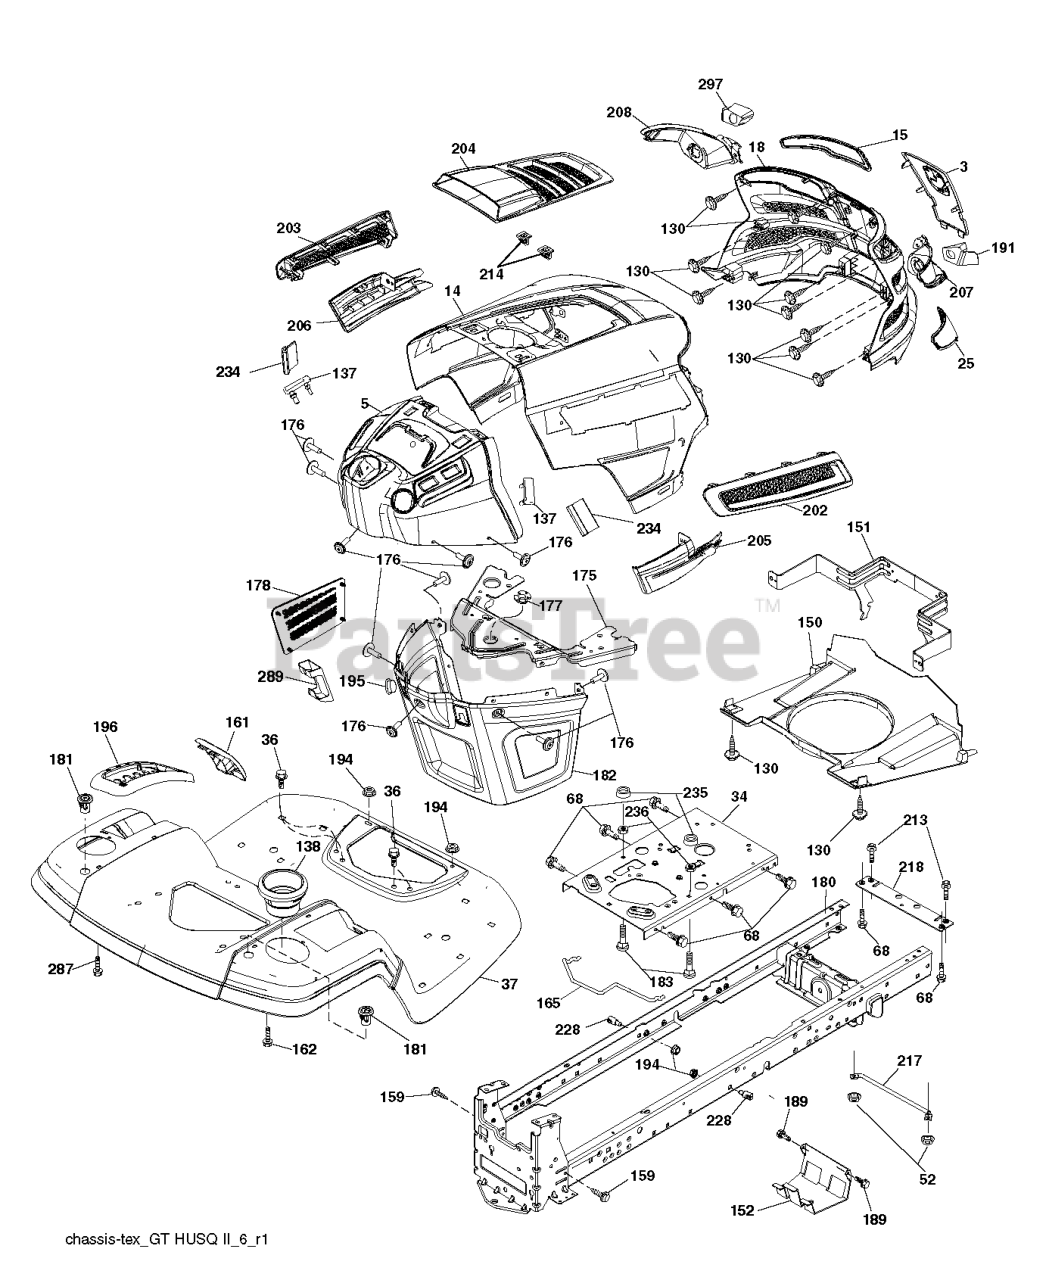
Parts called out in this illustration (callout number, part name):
3	APPLIQUE.SUBASM.GT.HUSQ.II
5	RP.DASH.UPP.GT2.SM.MC.CHOKE
14	HOOD.ASM.HUSQVARNA.GT.TEX.ORAN
15	LENS.HEADLIGHT.LH.GTII.2011
18	GRILLE.SUBASM.GT.HUSQ.II
25	LENS.HEADLIGHT.RH.GTII.2011
34	PLATE.ENGINE.WELDED.CHASSIS
36	SCREW 5/16"
37	FENDER.TLT.FS.W/CPH/FW/RSF.668
52	LOCKNUT
68	Screw 5/16-18 x 1/2 Hex, Self Tapping 5/16-18 x 1/2
130	SCREW.#10 X 0.750.BOS
137	BUMPER DASH
138	HOLDER.CUP.LT.GREY
150	AIR.DUCT.GTV2(2.54"RING HEIGHT
151	BRACKET.PIVOT.HOOD.GT.HUSQ.II
152	SHIELD.BROWNING.W/TEX
159	SCREW, 3/8-16X3/4
161	WINDOW.FUEL.LT.TEX.GREY
162	SCREW.HI-LO.CONSOLE
165	SUPPORT.TANK.REAR.W/TEX
175	PLATE.CROSSMEMBER.HUSQ
176	SCREW.#10-24X5/8.RN.QU
177	BUSHING, STEERING
178	CARGO.ASM.NET.TXGT.W/C
180	CHASSIS
181	BUSHING.MNT.FEND.CRGO.TEX.49
182	DASH.LOWER.COMMON.12V.ADAPTOR
183	BOLT.5/16-18X1-1/4 FULL THD
189	SCREW
191	INSERT.REFLECTIVE.RH.HUSQ.GTII
194	NUT LOCK HEX FLANGE 5/16-18
195	PLUG.HOLE.DASH.LOWER.12V.BLK
196	CONSOLE.ASM.DCKLFT.RBT.TLT.498
202	VENT.SIDE.RH.GT.HUSQ.II.
203	VENT.SIDE.LH.GT.HUSQ.II.498
204	VENT.TOP.HUSQ.GT2
205	SIDE.TRIM.RH.GT.HUSQ.II
206	SIDE.TRIM.LH.GT.HUSQ.II.GRAY
207	BEZEL LIGHT.RH.GT.II.MYLAR
208	BEZEL LIGHT.LH.GT.II.MYLAR
213	BOLT
214	CLIP.RETAINER.TINNER.
217	ROD.PIVOT.HOOD
218	X-PIECE.HOOD.STOP.NON/
228	STUD.FASTNER.W/ANTI-ROTATE
234	BUMPER.HOOD.TEX.HUSQVARNA
235	SPACER FENDER
236	NUT.CENTERLOCK.5/16-
287	SCREW 1/4X20
289	PLUG.N/CRUISE.COMMON.YT/GT.BLK
297	INSERT.REFLECTIVE.LH.HUSQ.GTII
